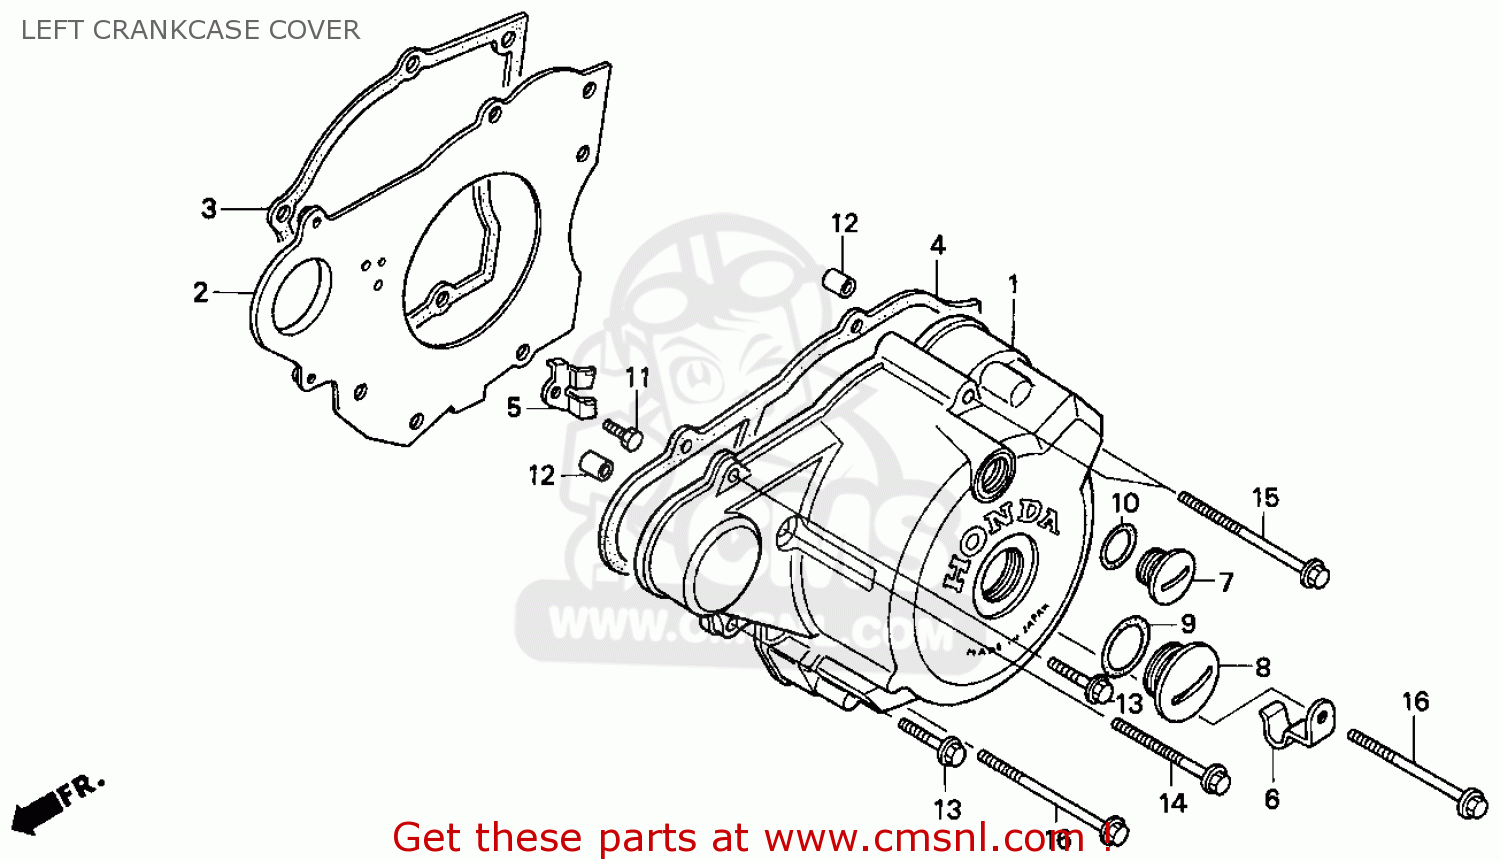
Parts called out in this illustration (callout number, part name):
1	COVER,L,CRANKCASE
2	SPACER,L,SIDE
3	GASKET,L.CRANKCAS (NAS)
4	GASKET,L.SIDE SPA (NAS)
5	PLATE,SPROCKET
6	CLIP,START CABLE
7	CAP,A.C.GENERATOR
8	CAP,30MM
9	O RING 27.4-2.4
10	O-RING,13.8X2.5
11	BOLT,HEX.,6X10
13	BOLT FLANG 6X20
14	BOLT,FLANGE,SH,6X40
15	BOLT,FLANGE,6X50
16	BOLT,FLANGE SH 6X65
